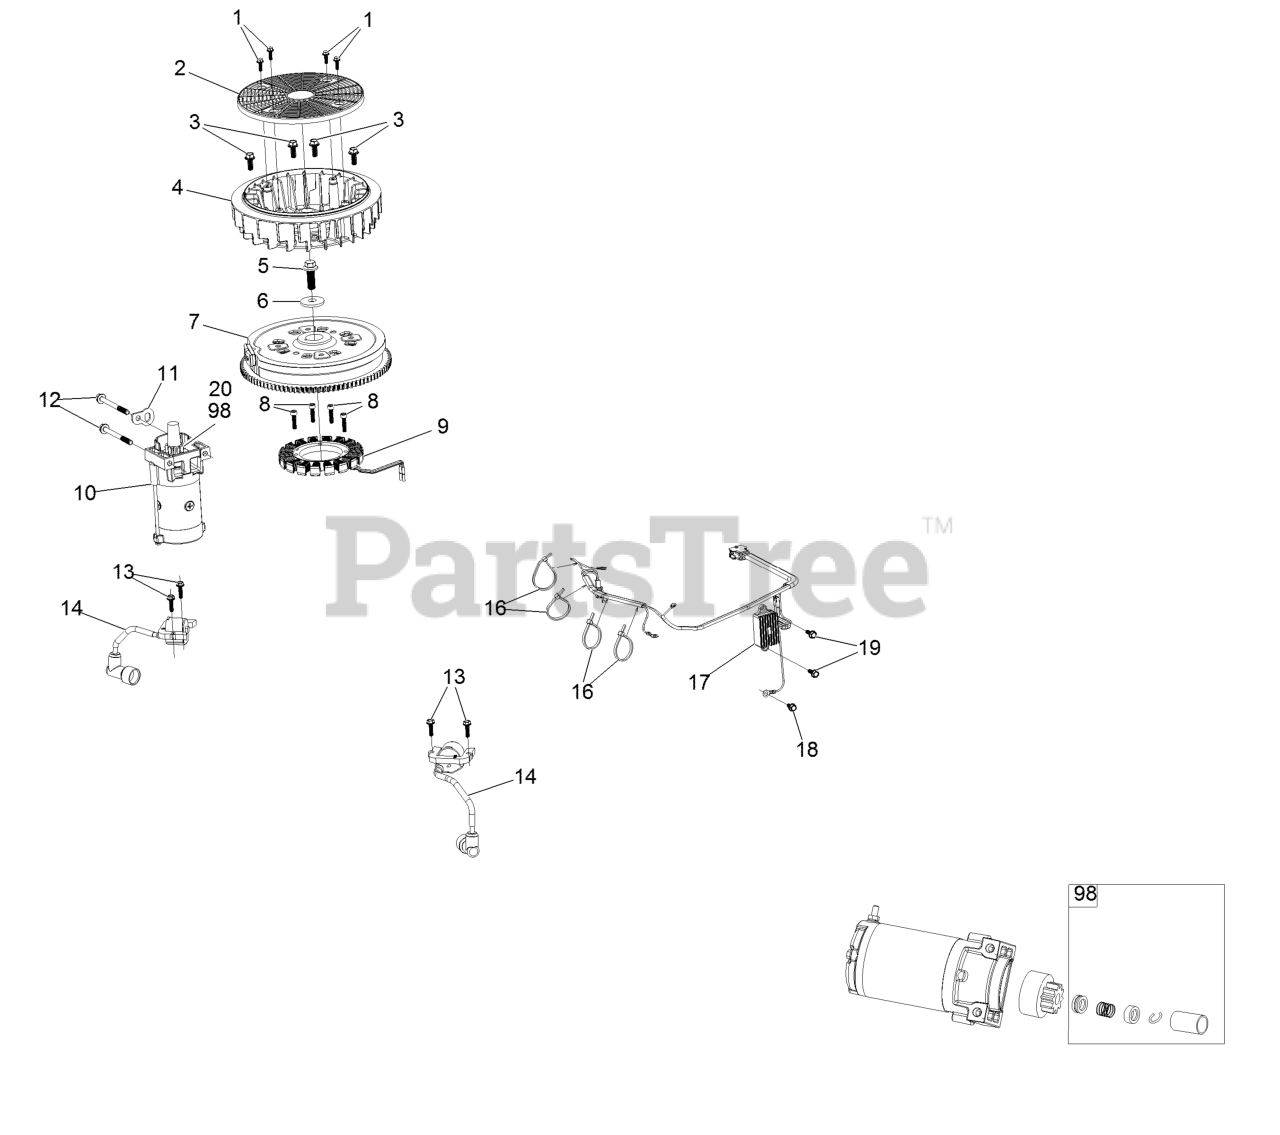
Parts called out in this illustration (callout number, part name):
1	Screw-HWH
2	Screen-Rotating
3	Screw-HWH
4	Fan-Cooling
5	Screw-HWH
6	Washer-Flat
7	Flywheel
8	Screw-HSH
9	Alternator
10	Motor-Starter
11	Bracket-Lift
12	Screw-HHF
13	Bolt-Flange
14	Ignition Coil ASM
16	Tie-Zip
17	Regulator-Voltage, W/Harness
18	Screw-HHF
19	Screw-HHF
20	Pinion-Starter
98	Starter Repair Kit
